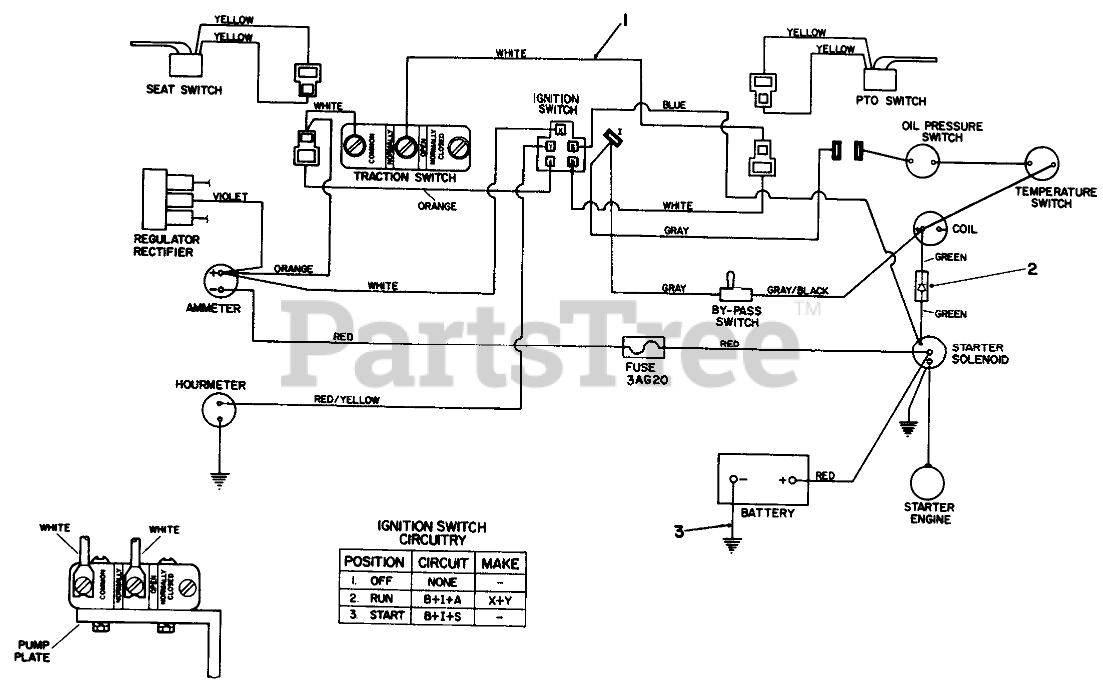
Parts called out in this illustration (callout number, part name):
1	Wire Harness (Incl. Ref. # 2)
2	JUMPER WIRE ASM
3	BATTERY GROUND WIRE
